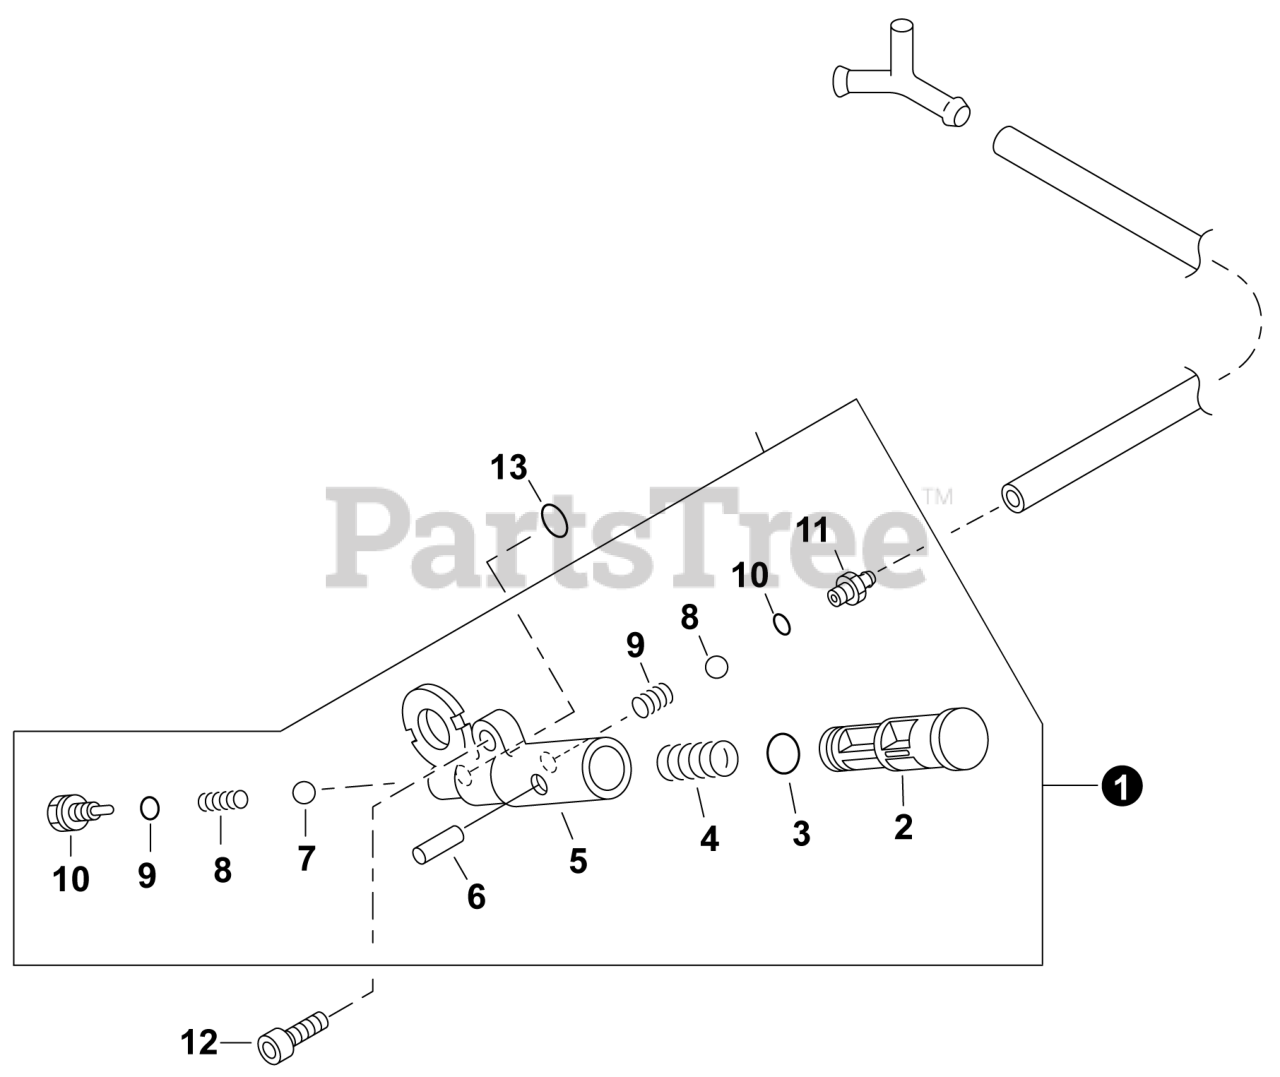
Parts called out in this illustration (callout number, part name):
1	O-RING 3
2	OIL PUMP ASSY - BLACK
3	PISTON, OIL PUMP - BLACK
4	O-RING 7 MM
6	BODY, OIL PUMP
7	PIN, SPRING 2×16
8	VALVE, BALL
9	SPRING, COMPRESSION
11	ADAPTOR, OIL PUMP
12	CONNECTOR, PIPE
13	BOLT 5×20
